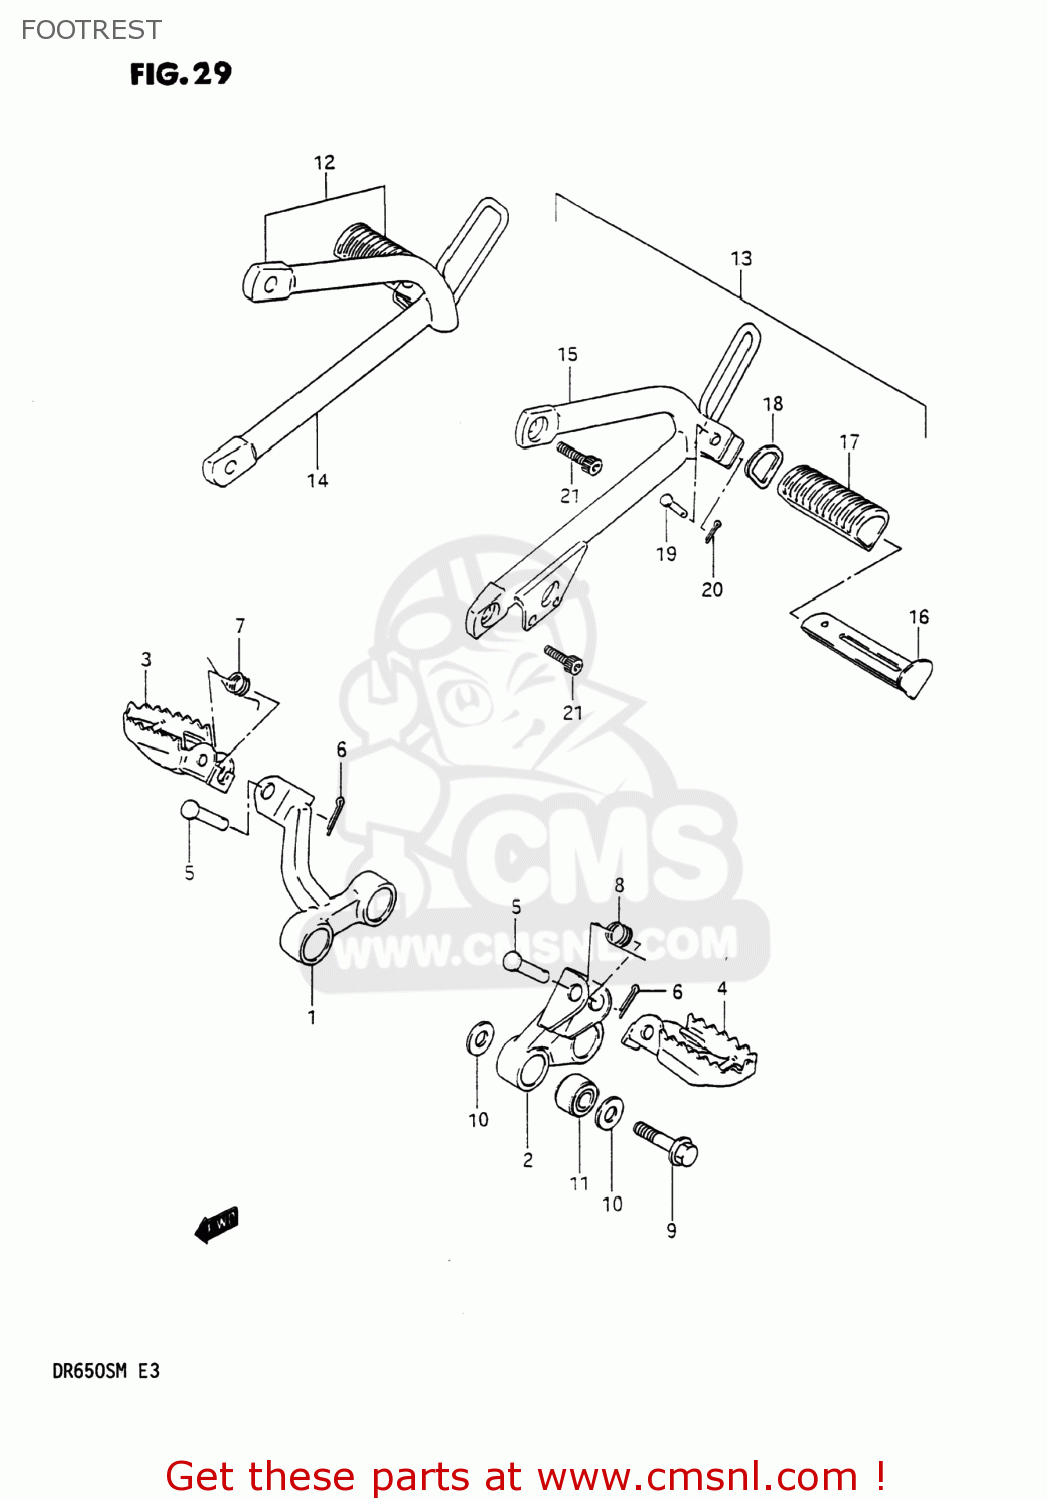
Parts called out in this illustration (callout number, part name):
1	BAR,FRONT FOOTREST,RIGHT
2	BAR,FRONT FOOTREST,LEFT
3	FOOTREST,FRONT,RIGHT
4	FOOTREST,FRONT,LEFT
5	PIN
6	PIN 20X20
7	SPRING
8	SPRING
9	BOLT(10X50)
10	WASHER
11	BUSH(10.2X25X19)
12	FOOTREST ASSEMBLY,PILLION
13	FOOTREST ASSEMBLY,PILLION
14	HOLDER,PILLION FOOTREST
15	HOLDER COMP,PILLION FOOTREST
16	BAR COMP,PILLION FOOTREST
17	RUBBER,PILLION FOOTREST
18	WASHER,PILLION FOOTREST
19	PIN
20	PIN
21	BOLT
